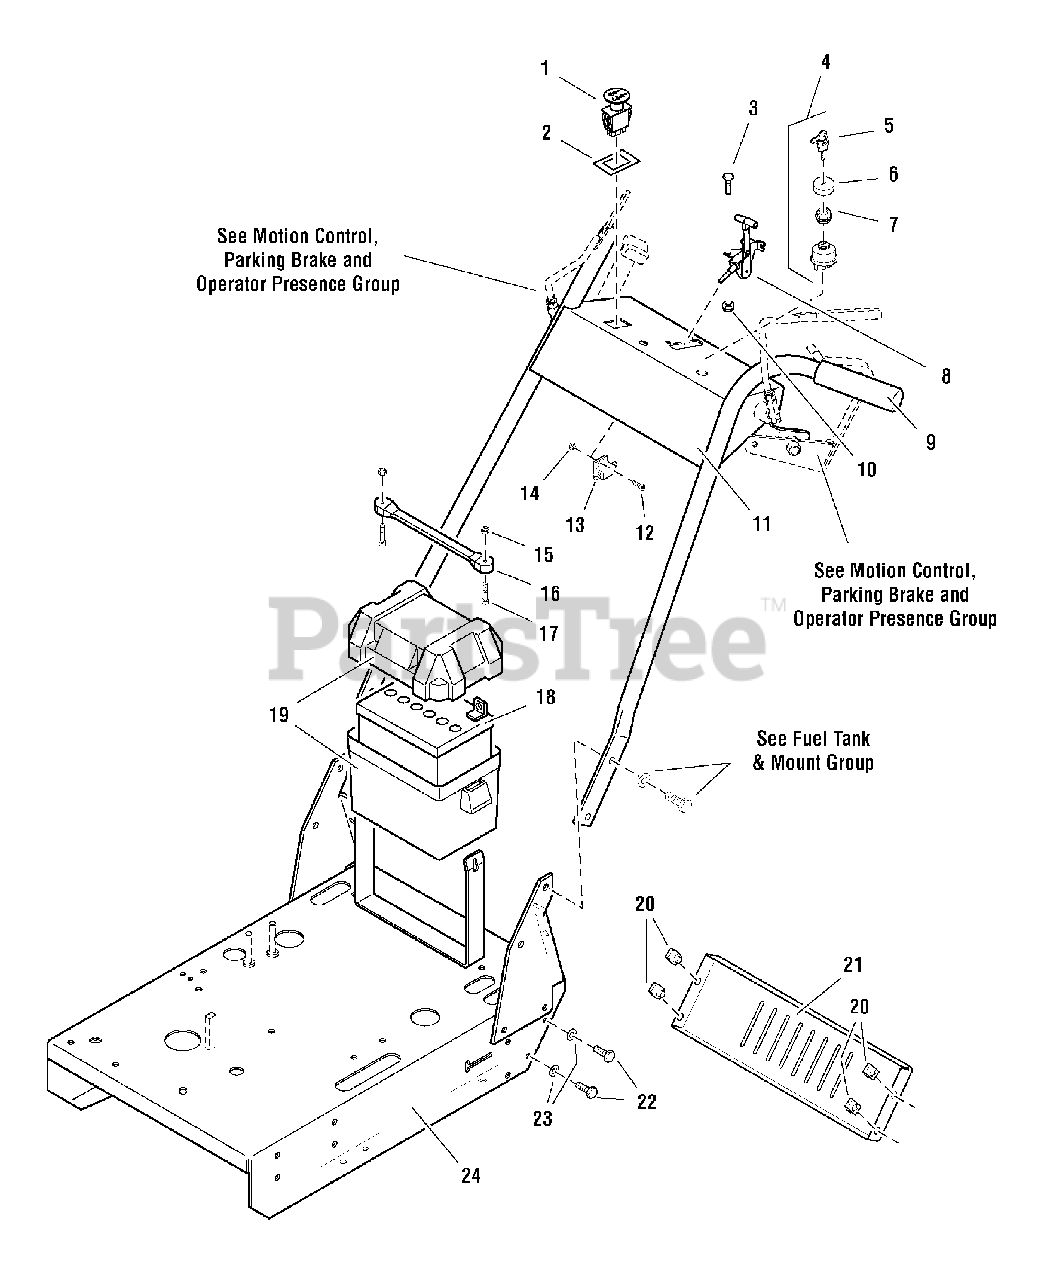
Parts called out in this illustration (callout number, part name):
1	SWITCH, PTO, Push/Pull
2	SWITCH RETAINER RING
3	CAPSCREW, Hex Head, 1/4-20 x 3/4
4	SWITCH, Ignition, Complete (includes Ref 5 - 7)
5	KEY, Ignition, Molded (set of 2)
7	PLASTIC NUT
8	CABLE, Throttle Control
9	FOAM GRIP
10	NUT, Hex Nylon Lock, 1/4-20
11	HANDLE BAR ASSEMBLY
12	SCREW, Phillips Head, #10-24 x 1/2
14	NUT, Hex, #10-24
15	NUT, Nylock, #10-24
16	RUBBER STRAP
17	SCREW, Phillips Head, #10-24 x 1
18	BATTERY, Lawn & Garden, 12V (BCIU1, 340 CCA)
19	BATTERY BOX
20	BODY CLIP, 5/16-18
21	REAR SHIELD
22	CAPSCREW, Hex Head, 5/16-18 x 3/4
23	WASHER, 5/16
24	ENGINE DECK ASSEMBLY
